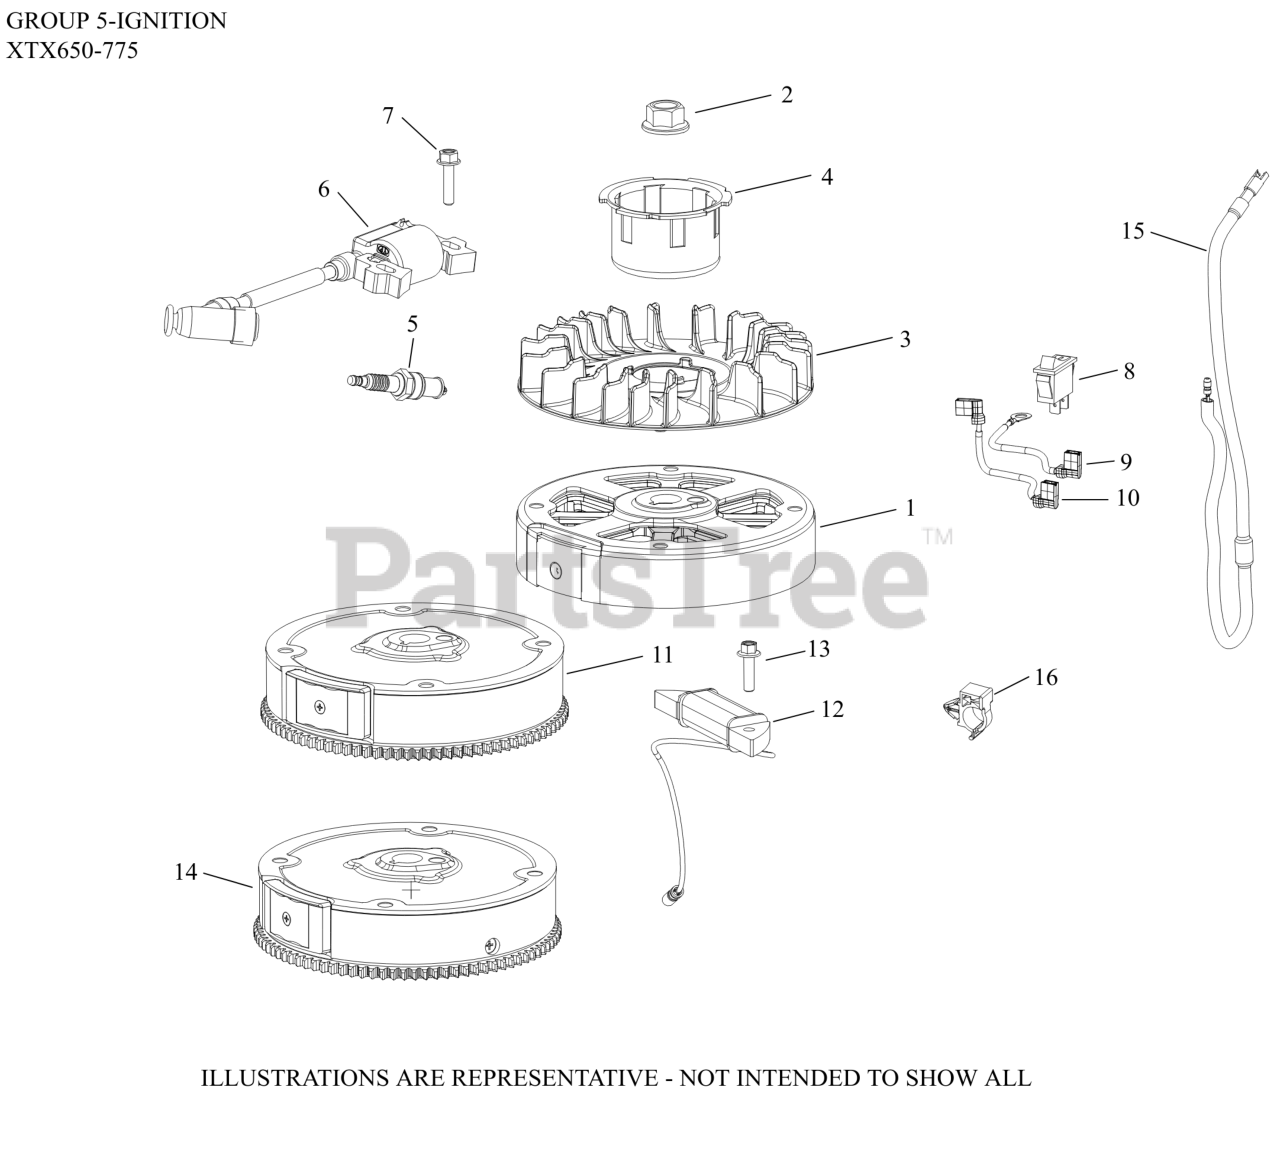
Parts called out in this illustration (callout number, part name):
1	FLYWHEEL ASSEMBLY
2	NUT, FLYWHEEL (W/SERRATIONS)
3	FAN, FLYWHEEL
4	CUP, DRIVE - (#1410905S)
5	PLUG SPARK 12MM RFI
6	MODULE IGN (#1458416S)
7	SCREW, M6 X 25-(#25086436S)
